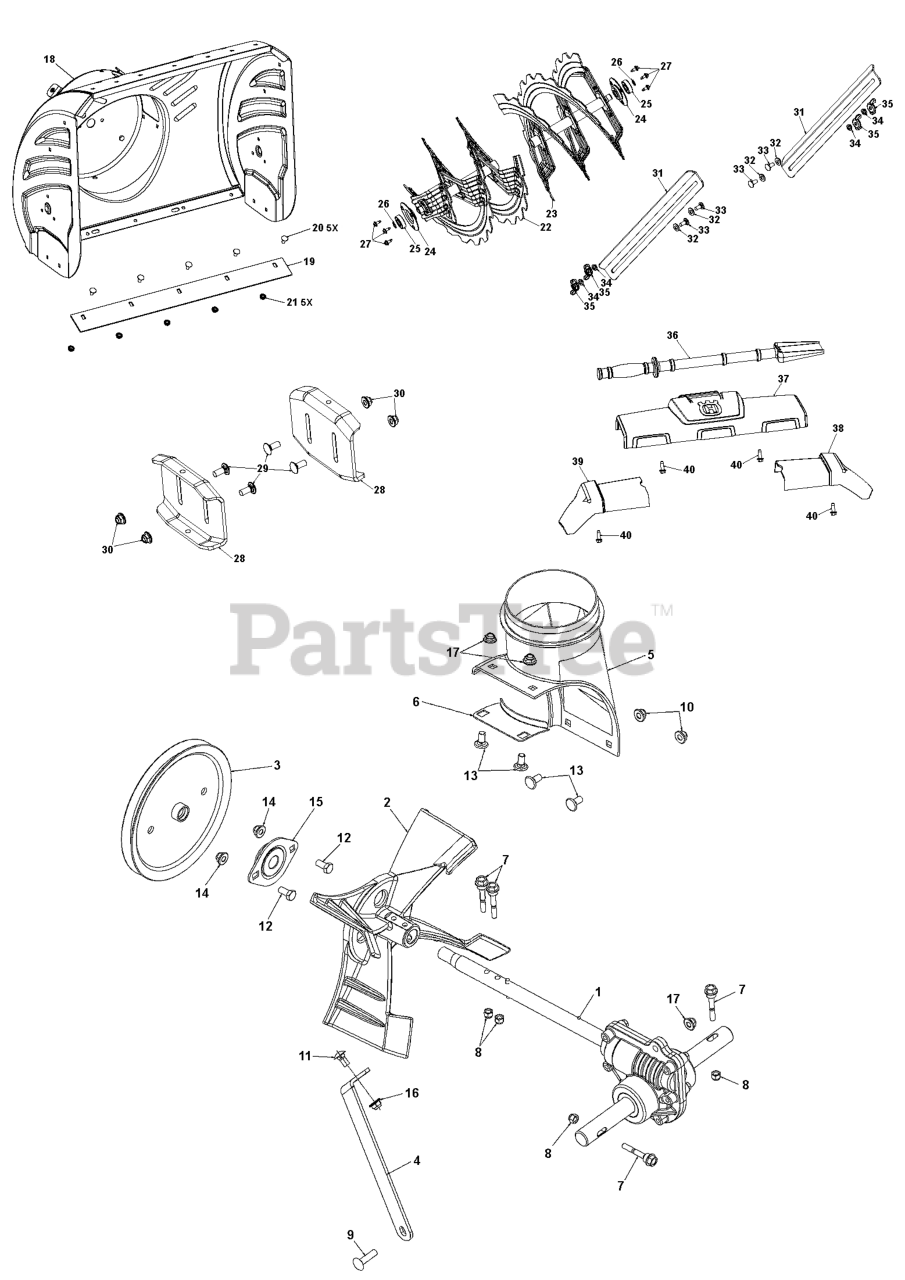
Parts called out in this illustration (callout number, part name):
1	GEAR BOX ASM CAST
2	IMPELLER CAST.IRON.12IN MS 417
3	PULLEY SCREW ON 7.9
4	SUPPORT.GEARBOX.LS.498
5	CHUTE.DISCHARGE.BASE
6	BRACKET, CORNER DISCHARGE
7	BOLT.1/4-20 X 1-13/16 SHEAR
8	LOCKNUT.NYLOC.1/4-20
9	BOLT.CARRIAGE.5/16-18
10	NUT HEX FLG NYLOCK BLK 5_16-1
11	BOLT CAR BLK 5/16-18 X 5/8
12	BOLT, HEX HEAD 5/16-18
13	BOLT CARR WAFER BLK 5_16-18 X
14	NUTNYLOK.FLRANGE.5/16-18
15	BEARING FLANGE
16	NUT HEX FLG NYLOCK BLK 5_16-1
16	NUT.LOCK.5/16-18
17	BEARING FLANGE
17	NUT HEX FLG NYLOCK BLK 5_16-1
18	KIT.AUG.HOUSING.581976902.668
18	HOUSING.AUGER.30.LS.ORANGE
19	PLATE.SHAVE.30.LS.SNOW.BLACK
20	BOLT
21	NUT.FLANGE.5/16
22	AUGER.RIB.30.RH.LS.GREY
22	AUGER.RIB.30.RH.LS.BLACK
23	AUGER.RIB.30.LH.LS.GREY
23	AUGER.RIB.30.LH.LS.BLACK
24	SUPPORT.BEARING.SINGLE.STAGE.B
26	RETAINING RING LT
27	HEX.WASHER.HEAD 1/4-20 X .65
28	PLATE.SKID.SHOE.COMPOSITE
28	SKID PLATE
29	BOLT CARR BLK 5_16-18 X .750
29	BOLT.CARR.5/16-18X1.BLACK
30	NUT HEX FLG NYLOCK BLK 5_16-1
30	NUT.HEX.FL 5/16-18 TOP LCK BLK
31	DRIFT CUTTER BAR
32	WASHER, NYLON FRICTION
33	BOLT
34	WASHER.LOCK.HVY.HLCL.SPR.5/16
35	NUT WING PM
36	CLEAN OUT TOOL
37	TRIM AUGER.HOUSING.FRONT.ASM
38	TRIM AUGER.HOUSING.WING.RH MS
39	TRIM AUGER.HOUSING.WING.LH MS
40	SCREW HEXWSHR 1/4-20X3/4
